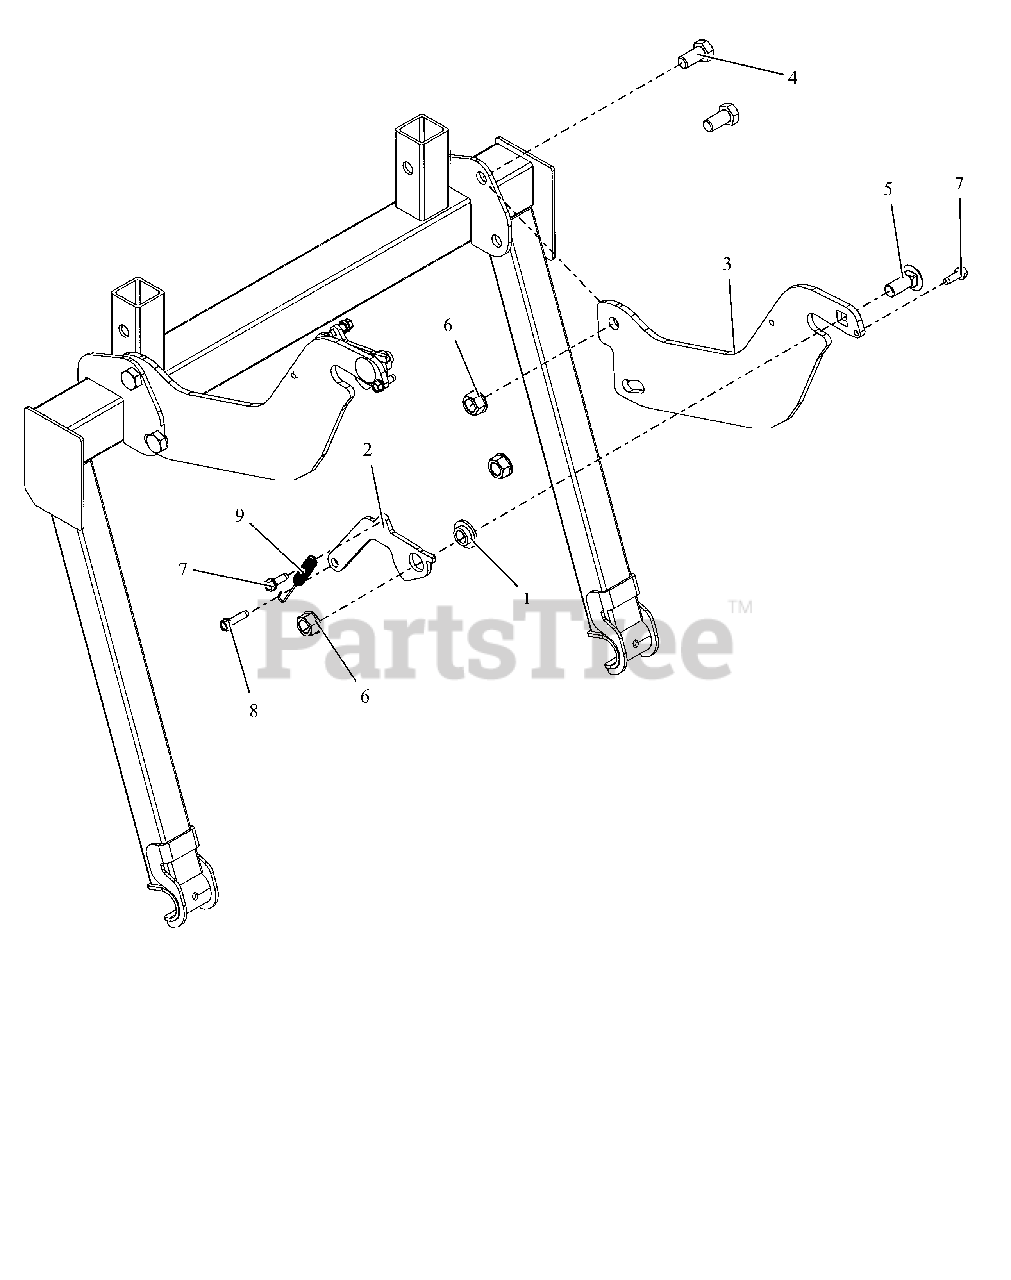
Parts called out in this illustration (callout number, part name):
1	BSHG-FLG .515X.750X.310X1.120
2	BAGGER, LATCH - BLACK
3	LATCH, BAGGER MTG ARMS
4	@BLT-HEX .50-13X1.00 GR5 YWZC
5	@BLT-RDHDSQNK .50-13X1.25 G5YZ
6	@NUT-LK-TOP-FLG .50-13 YWZC
7	SCR-TAP-PM .25-20X.75 TR YWZ
8	@SCR-TAP .25-20X1.00 HWH TR YZ
9	SG-TENS .043X.44X3.31 WLD 5.8
